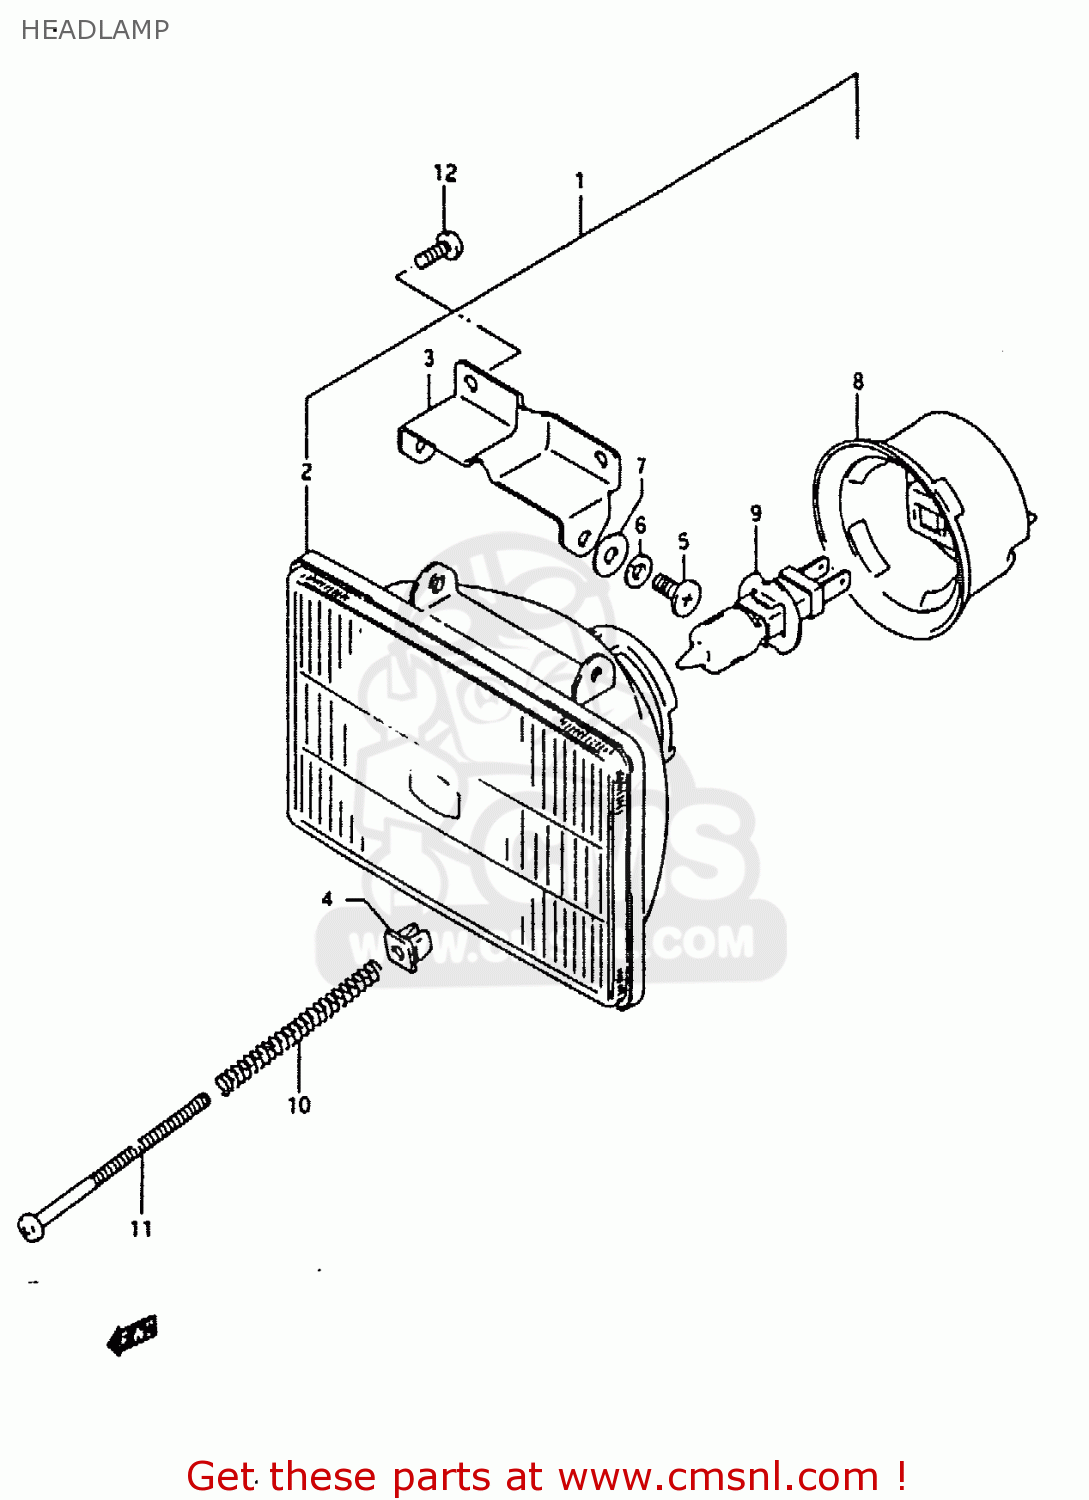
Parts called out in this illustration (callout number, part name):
1	HEADLAMP ASSY
2	UNIT,LAMP
3	BRACKET,LAMP
4	NUT,ADJUSTING
5	SCREW
6	WASHER,LOCK
7	WASHER
8	COVER,SOCKET
9	BULB (12V,55W)
10	SPRING,HEAD LAMP ADJUSTER
11	SCREW(4X45)
12	SCREW
